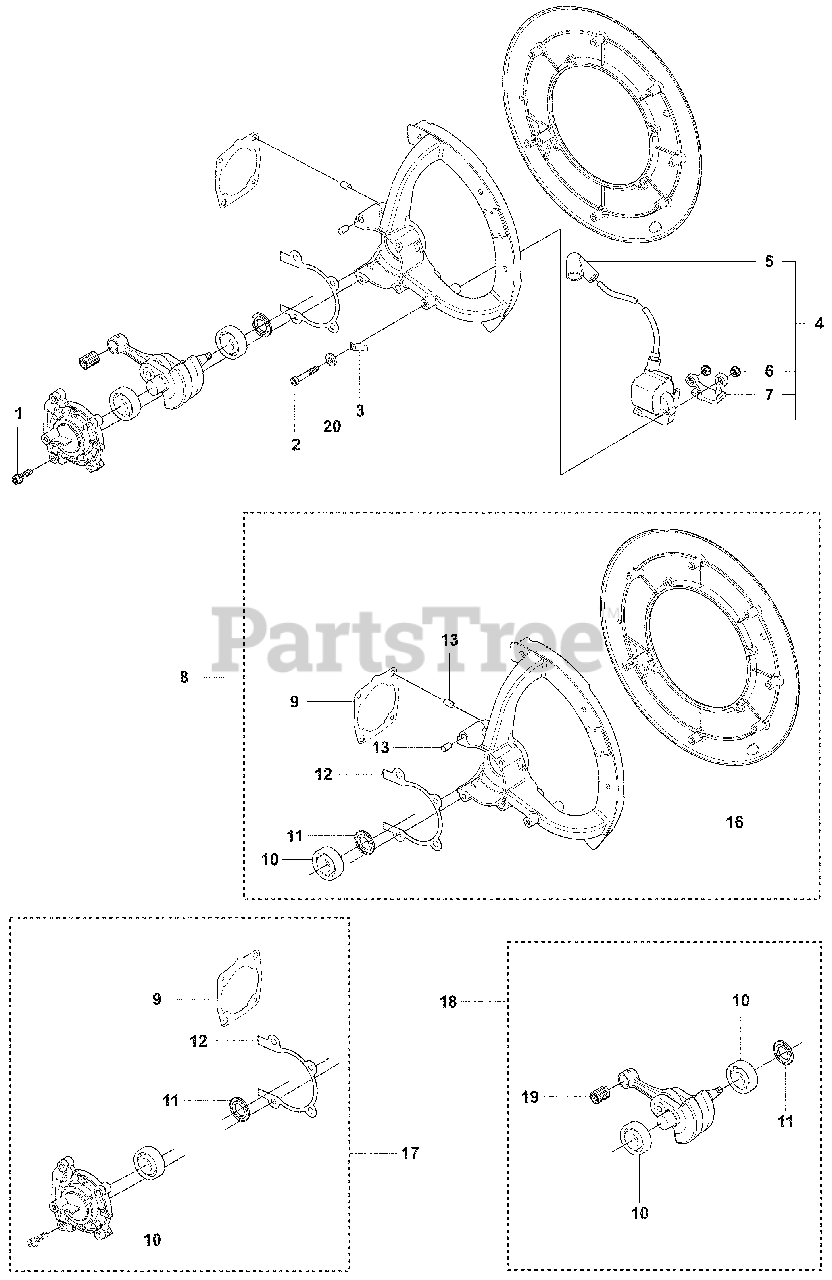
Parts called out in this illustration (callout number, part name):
1	Screw, MC6S 5 X 35
3	FLAT PIN
4	Ignition Module System
5	Spark Plug Connection Kit
8	CRANKCASE KIT
10	Ball Bearing, 6202C3 SK
13	Guide Bushing
18	CRANKSHAFT
19	Needle Bearing Piston Pin, 12 X 1
20	Washer, 4.2 X 9
